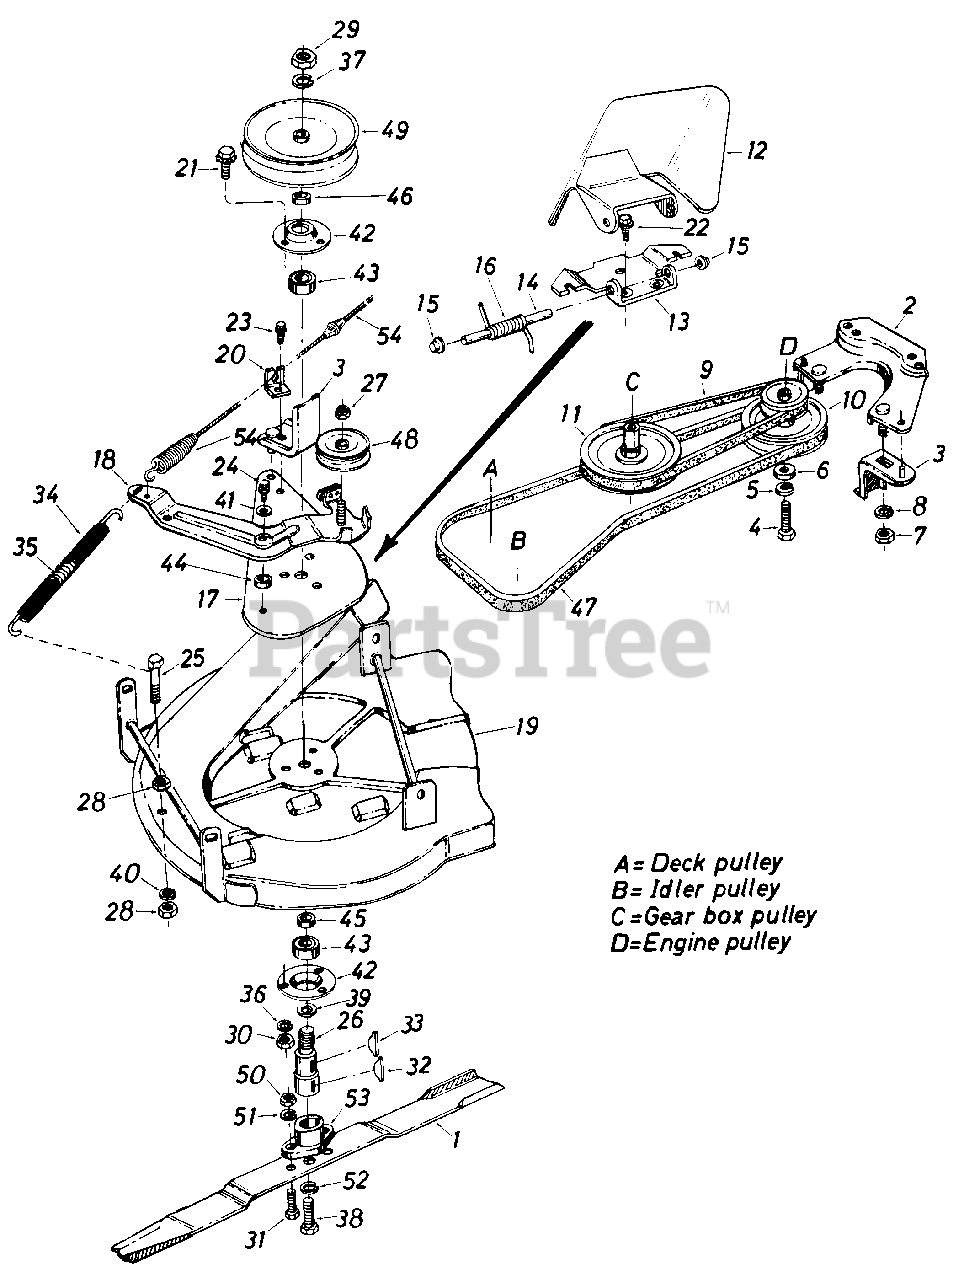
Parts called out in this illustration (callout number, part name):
1	26" Blade
2	Belt Guard Cup Ass'y.
3	Belt Keeper Ass'y.
4	Hex Bolt 3/8-24 x 1.00" Lg.*
5	L-Wash. 3/8" I.D.
6	Fl-Wash. .406" I.D. x 1.25" O.D.
7	Hex Nut 5/16-18 Thd.*
8	L-Wash. 5/16" I.D.*
9	3V-Belt 28" Lg.
10	Double Pulley
11	3/8" V-Pulley .502" I.D. x 6.5" O.D.
12	Chute Cover Ass'y. Comp.
13	Adapter Plate
15	Cap Speed Nut 1/4" Rod
16	Torsion Spring
17	Deck Belt Guard Plate
18	Deck Idler Brkt. Ass'y.
19	26" Deck Ass'y.
20	Cable Support Brkt.
21	Hex Sems Bolt 5/16-18 x 1.00" Lg.
22	Hex Wash. S-Tap Scr. 1/4-20 0 x .50" Lg.
23	Hex Wash. Hd. B-Tap Scr. 5/16-18 x .50" Lg.
24	Hex L-Bolt 5/16-18 x 1.00" Lg.
25	Hex Bolt 1/4-28 x 1.50" Lg.*
26	Blade Spindle
27	Hex Ins. L-Nut 3/8-24 Thd.
28	Hex Cent. L-Nut 1/4-28 Thd.
29	Hex Jam Nut 5/8-11 Thd.*
30	Hex Nut 5/16-18 Thd.*
31	Hex Bolt 5/16-24 x 1.00" Lg. (Grade 8)
32	#6 Hi-Pro Key 5/32 x 5/8" Dia.
33	#61 Hi-Pro Key 3/16" x 5/8" Dia.
34	Plastic Tube .52" I.D. x 7.0" Lg.
35	Ext. Spring .50" O.D. x 5.2" Lg.
36	L-Wash. 5/16" I.D.*
37	L-Wash. 5/8" I.D.*
38	Hex Bolt 3/8-24 x 1.50" Lg. (Grade 5)
39	Bearing Shield
40	L-Wash. 1/4" I.D.*
41	Fl-Wash. .330" I.D. x 1.25" O.D. x .120
42	Bearing Housing
43	Ball Brg. .787" I.D. x 1.85" O.D.
44	Spacer.315" I.D. x .75" O.D. x .37" Lg.
45	Spacer.836" I.D. x 1.01" O.D. x .320" Lg.
46	Spacer.630" I.D. x 1.135" O.D. x .195" Lg.
47	"V"-Belt-A Sec. x 59.0" Lg.
48	"V"-ld ler 3.06 " O.D.
49	5/8" V-Pulley .625" I.D. x 7.0" O.D.
50	Hex Nut 5/16-24 Thd.*
51	L-Wash. 5/16" I.D.*
52	L-Wash. 3/8" I.D. Heavy Duty
53	Blade Adapter Kit
54	Clutch Cable 56.0"
